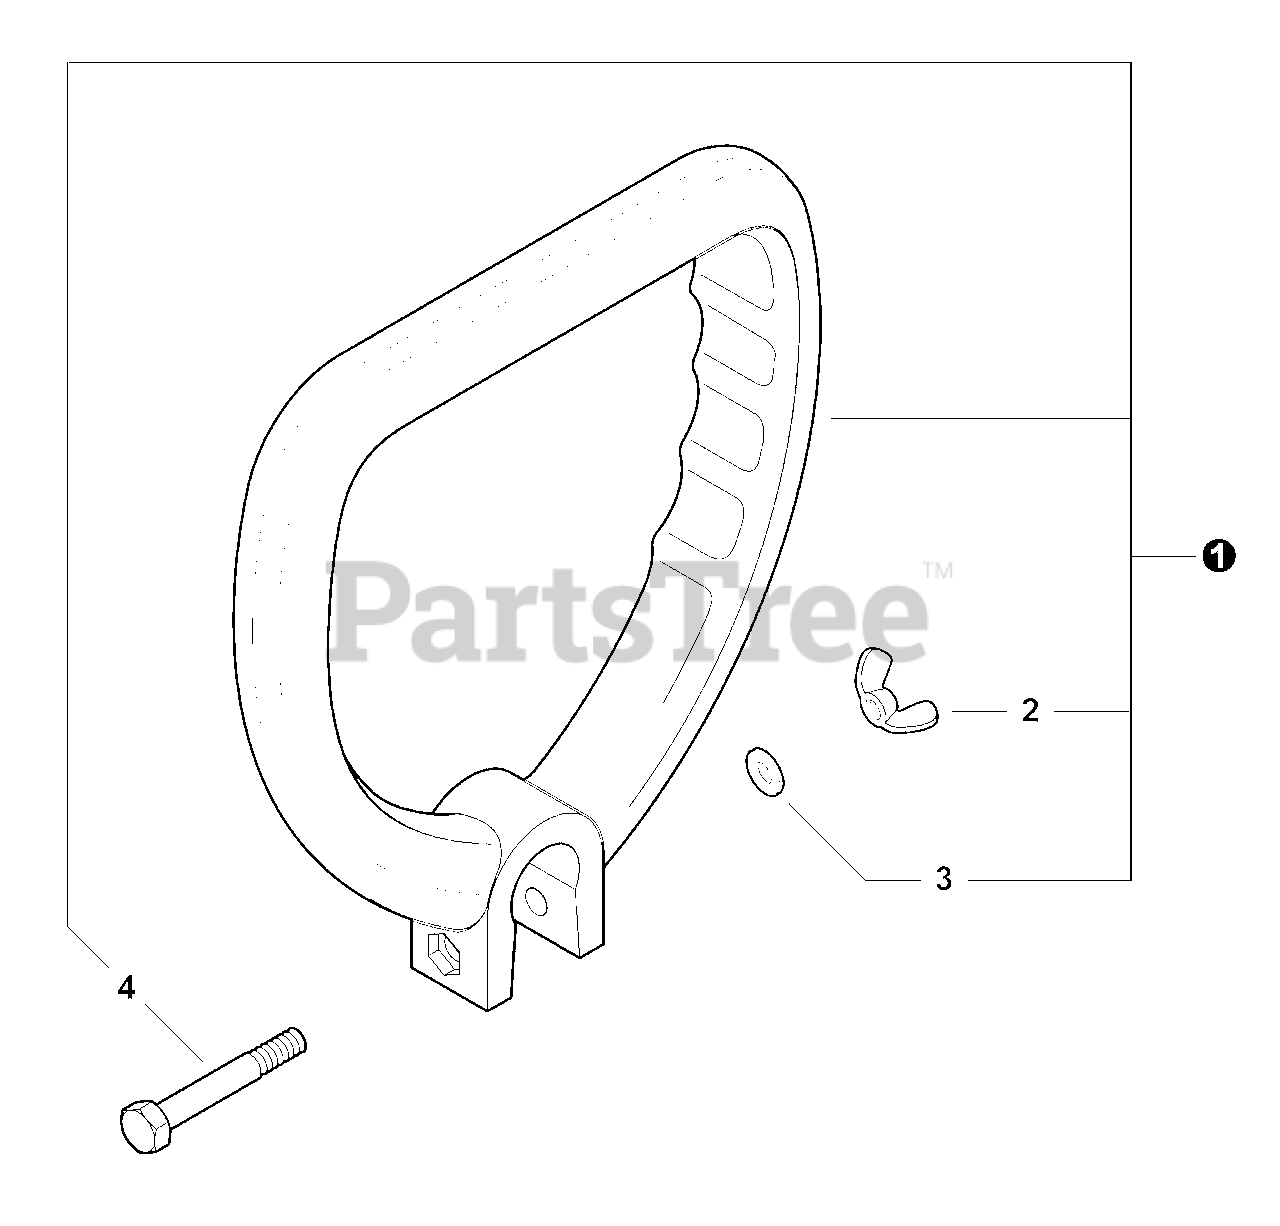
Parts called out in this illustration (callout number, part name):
1	FRONT HANDLE ASSY
2	WINGNUT - 1/4-20
3	WASHER - 1/4"
4	BOLT - 1/4-20 X 1-3/4"
